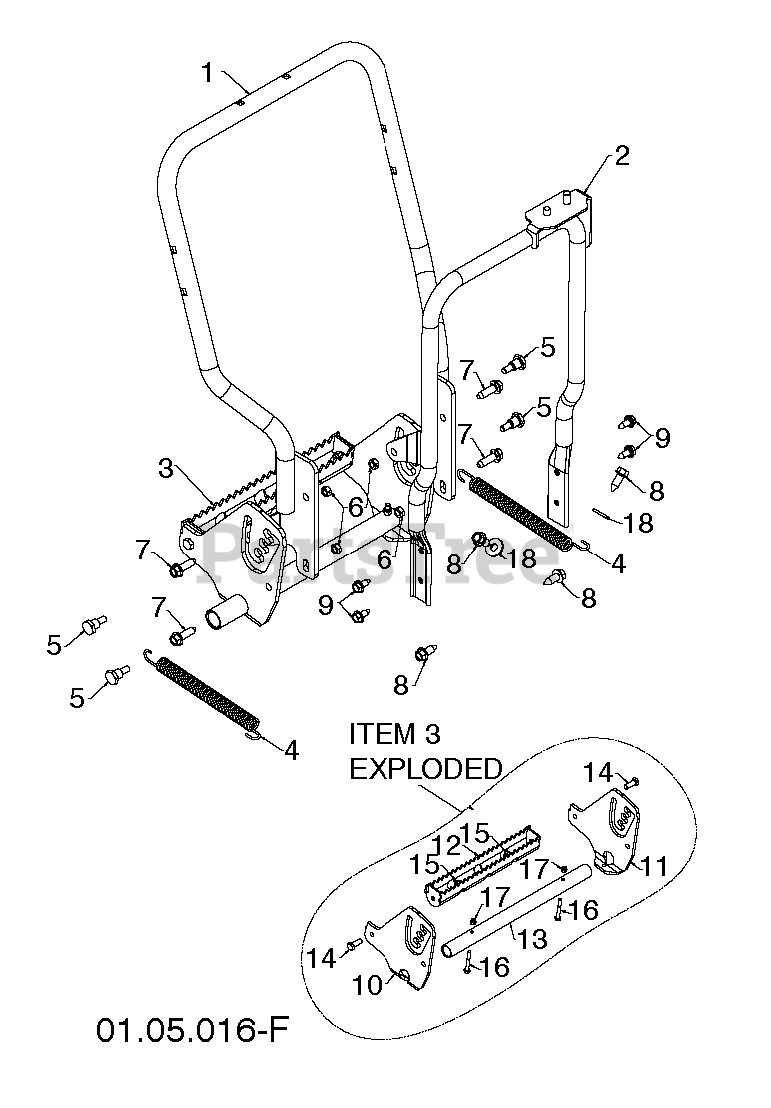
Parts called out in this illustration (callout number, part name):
1	HANDLE.ASM.LOWER.TRACK.GREY
2	SUPPORT.WELDMENT.ROTATOR.BLACK
3	PLATE.FOOT.ASM.SNOW
4	SPRING.EXTENSION.TRACK.SNOW
5	SHOULDERBOLT5/1618
6	NUT.CENTERLOCK.5/16-
7	SCREW.3/8-16
8	SCREW 3/8-16X1
9	BOLT.5/16HEX.WHS.HD
10	FOOT.ADJUST.PLATE.GUIDE.RH.SNO
11	FOOT.ADJUST.PLATE.GUIDE.LH.SNO
12	TRACK.FOOT.ADJ.ASM.SNOW
13	TUBE.ANTI-ROTATE.TRACK
15	NUT
16	BOLT.HEX.FINISHED.1/4-20
17	LOCKNUT.NYLOC.1/4-20
